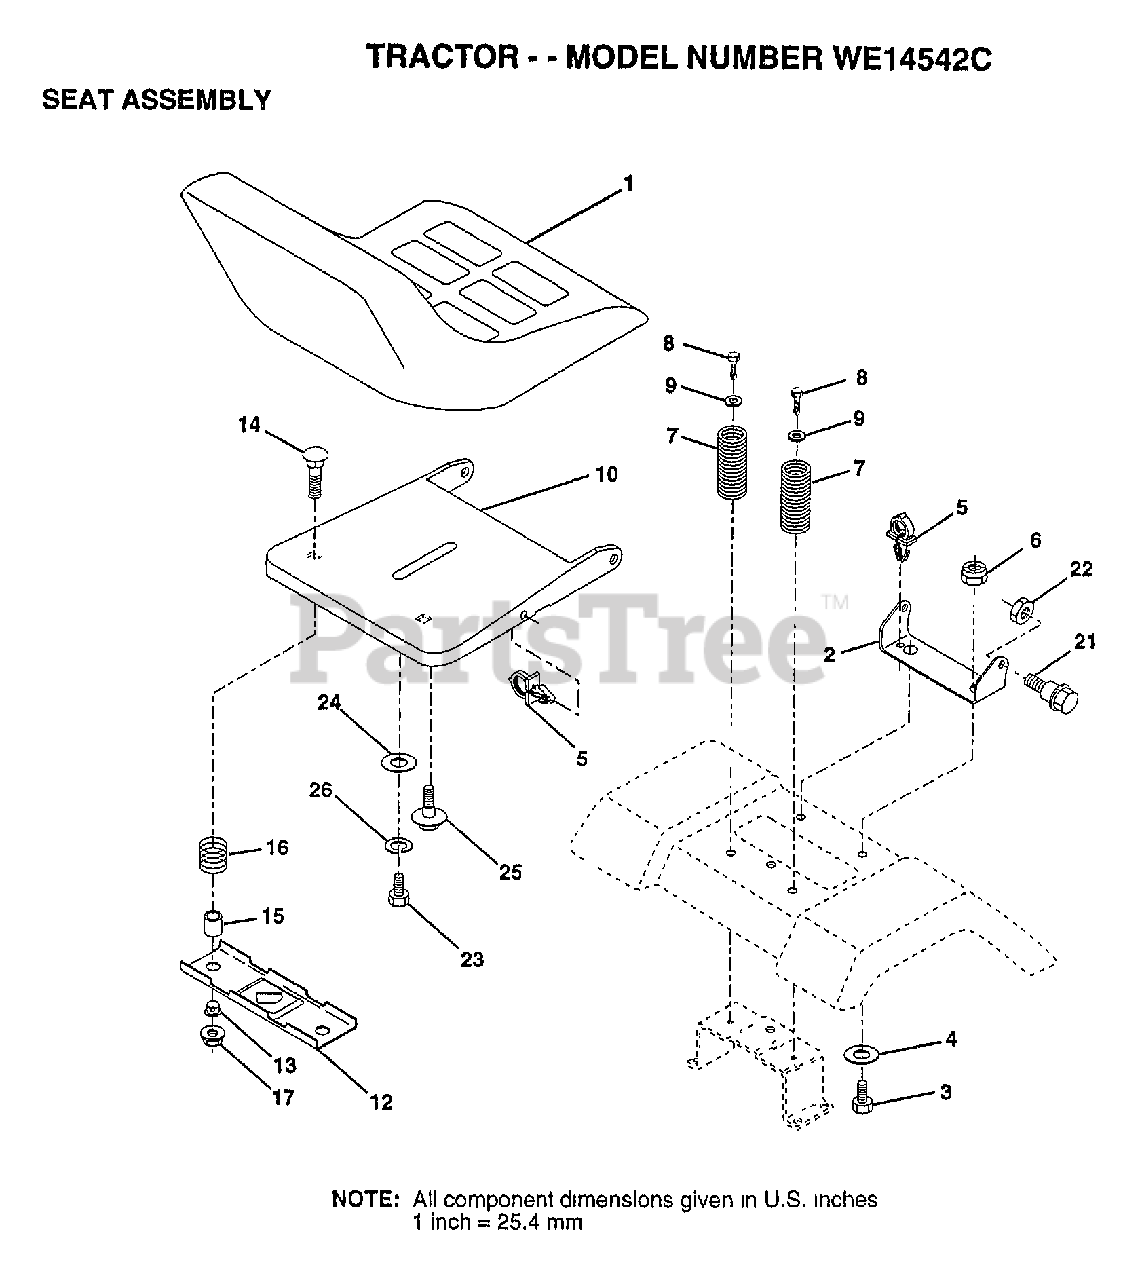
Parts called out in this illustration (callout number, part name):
2	BRACKET PVT SEAT
3	BOLT
4	WASHER PM
5	CLIP.PUSH-IN.HING
6	NUT
7	SPRING COMPRESSIO
8	SCREW GTV
9	WASHER
10	PAN-SEAT
12	BRKT SWITCH
13	BUSHING
15	SPLIT SPACER
16	SPRING
21	"BOLT,SHOULDER"
22	NUT
23	BOLT
24	WASHER
25	"BOLT,SHOULDER"
26	LOCKWASHER
